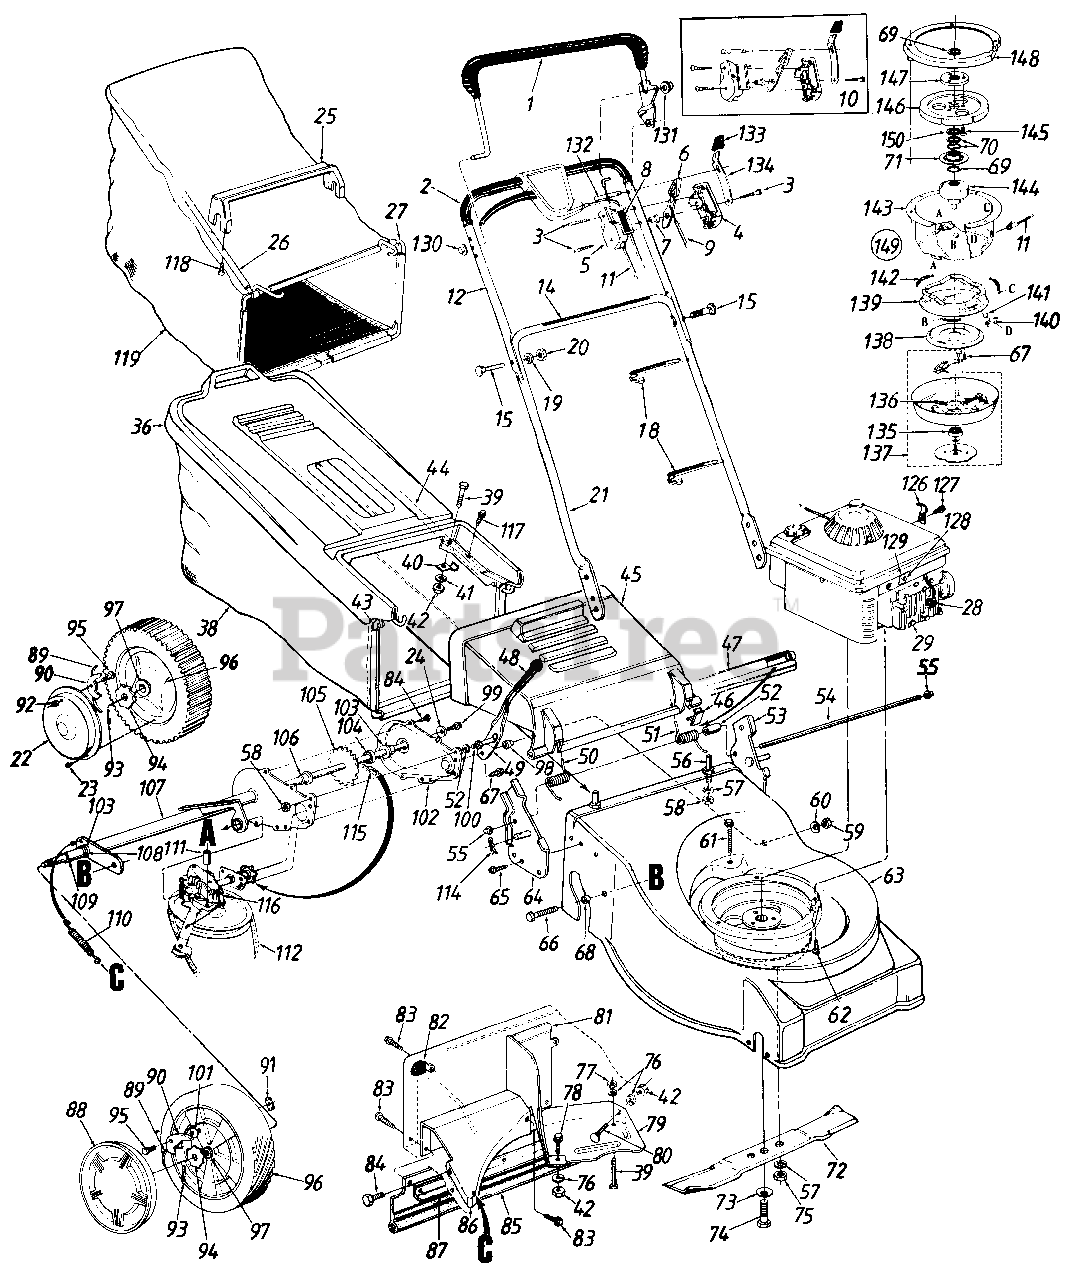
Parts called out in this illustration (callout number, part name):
1	Control Handle Ass'y.
3	Truss Mach. B-Tap Scr. #12 x 1.5" Lg.
4	Control Panel Half
5	Clutch Panel Half
6	Throttle Control Lever
7	Control Disc Pin
8	Control Label-Throttle
9	Thrott e Wire-45" Lg.
10	Control Housing Comp.
11	Control Cable-52" Lg.
12	Upper Handle
14	Instruction Label-Handle
15	Curved Carriage Bolt 5/16-18 x 1.38" Lg.
18	Cable Tie
19	L-Wash. 5/16" I.D.
20	Hex Nut 5/16-18 Thd.
21	Lower Handle
22	Hub Cap
23	Pan Hd. Tap Scr. #12 x .50" Lg.
24	Bell-Wash. .265" I.D. x .75"
25	Bag Handle
26	Rear Catcher Frame
27	Front Catcher Frame
28	Spark Plug Boot
29	Engine
36	Hardtop Bag Cover
38	Grass Bag
39	Truss Mach. Scr. 1/4-20 x 1.0" Lg.
40	Mounting Clamp
41	Fl-Wash. .281" I.D. x .62"
42	Hex Nut 1/4-20 Thd.
43	Front Catcher Frame
44	Rear Catcher Frame
45	Chute Deflector
46	Deflector Plug
47	Seal-Extrusion
49	Spring Lever
50	Torsion Spring-R.H.
51	Torsion Spring-L.H.
52	Spacer.255" I.D.
53	Handle Brkt. Ass'y.-L.H.
54	Hinge Pin 17.75" Lg.
55	Cap Speed Nut
56	Shld. Pin 3/8-24 x 1.43" Lg.
57	L-Wash. 3/8" I.D.
58	Hex Jam Nut 3/8-24 Thd.
59	Hex L-Nut 3/8-24 Thd.
60	Bell-Wash. .38" I.D. x .88"
61	Hex Wash. Hd. Tap Scr. 1/4-20 x 1.5" Lg.
62	Hex L-Wash. Hd. Scr. 3/8-16 x 1.5" Lg.
63	21" DeckAss'y.
64	Handle Brkt. Ass'y.-R.H.
65	Hex L-Wash. Hd. AB-Tap Scr. 1/4 x .62" Lg.
66	Hex Wash. Hd. Tap Scr. 3/8-16 x .75" Lg.
67	Hex Wash. Hd. Tap Scr. 1/4-20 x .5" Lg .
68	Spacer.385" I.D.
69	Serrated Washer 1.0" I.D.
70	Wave Washer 1.005" I.D.
71	Serrated Pulley Half
72	21" Blade
73	Bell-Wash. .46" I.D. x .88"
74	Hex Bolt 7/16-20 x 2.0" Lg. (Grade 5)
75	Hex Nut 3/8-24 Thd. (Grade 8)
76	L-Wash. 1/4" I.D.
77	Hex Jam Nut 1/4-20 Thd.
78	Hex Bolt 1/4-20 x .85" Lg.
79	Rear Belt Baffle
80	Carr. Bolt 1/4-20 x .50" Lg.
83	Torx Mach. AB-Tap Scr. 1/4 x .62" Lg.
84	Hex B-Tap Scr. 1/4 x .38" Lg.
85	Rear Flap
89	Plastic Spring
90	Pawl.345" I.D.
91	Weld Nut 1/4-20 Thd.
92	Hex Ins. L-Nut 1/4-20 Thd.
93	Cotter Pin 1/8" Dia.
94	Ratchet Wheel 1.62" O.D.
95	Shld. Bolt .342" Dia. x .268"
96	Wheel Ass'y. Comp.-Rear
97	Flange Ball bearing 1/2" I.D.
98	Shld. Spacer. 50" Dia.
99	Hex Bolt 1/4-20 x .62" Lg. (Grade 5)
100	Shld. Pin 3/8-24 x 1.43" Lg.
101	Bell-Wash. .265" I.D. x .75"
102	Chain Cover Ass'y.
103	Hex Flange Brg. .506" I.D.
104	Fl-Wash. .531" I.D. x .93'
105	Rear Axle Ass'y.
106	Hex Flange Bearlng
109	Spacer. 513" I.D.
110	Extension Spring 3.8" Lg.
111	Spacer.325" I.D.
112	V-Belt
114	Internal Cotter Pin 5/16" Dia.
115	#48 Chain .50" Pitch x 30 Links
116	Transmission Comp.
117	Hex AB-Tap Scr. 1/4 x .62" Lg.
118	Hex AB-Tap Scr. #12 x 1.25" L9
119	Grass Bag
126	Cable Clamp
127	Hex B-Tap Scr. #10 x .38" Lg.
128	Hex B-Tap Scr. #10 x .62" Lg.
129	Cable Clamp
130	Push Cap
131	Push Cap
132	Lock Pin .314" Dia. x 1.75"
133	Spring Lever Knob
134	Lockout Spring
135	Ball Brg. .669" I.D. x 1.574"
136	Comp. Spring .35" O.D. x 2.0" Lg.
137	Clutch Blade Housing Ass'y.
138	Clutch Cone
139	Brake Cup Cone
140	Ball Block
141	Steel Ball .50" Dia.
142	Ext. Spring 1.75" Lg.
143	Clutch Housing
144	Fixed Pulley Adapter
145	Flat Hd. Tap Scr. 1/4-20 x .625" Lg.
146	Flywheel
147	Flywheel Adapter
148	Engine Mounting Plate Cover
149	Blade Brake Clutch Ass'y. Comp.
150	Serrated Wash. l" I.D.
